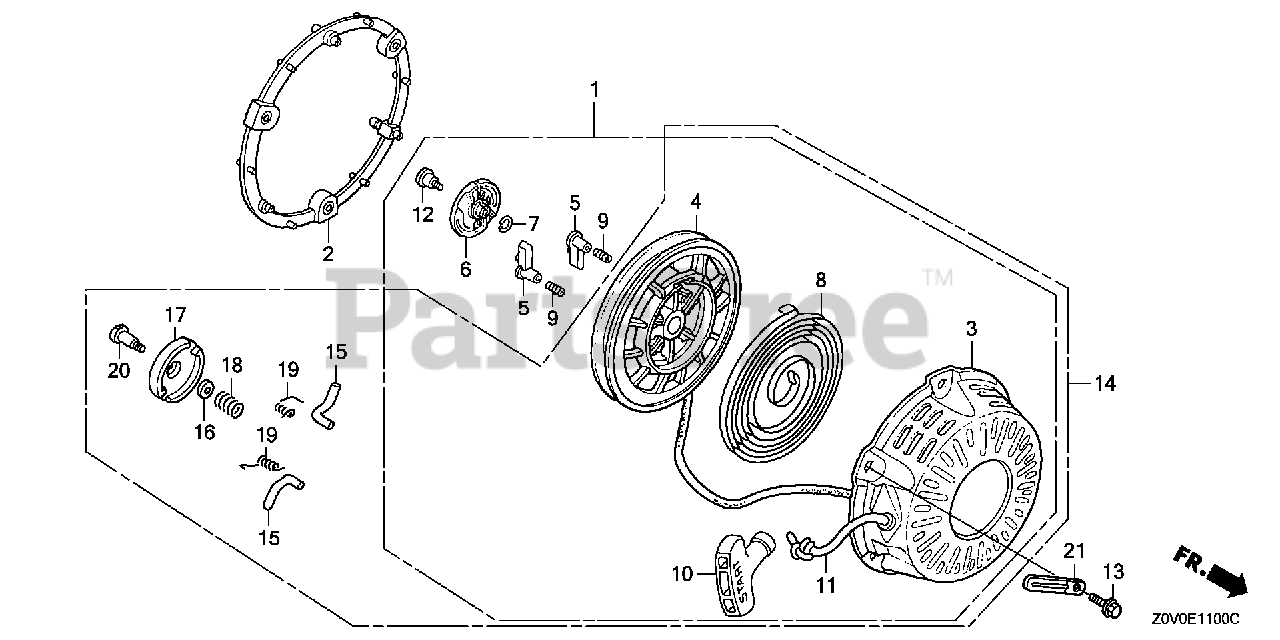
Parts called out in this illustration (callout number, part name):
2	SPACER, RECOIL STARTER MOUNTING *NH1* (BLACK)
2	SPACER, RECOIL STARTER MOUNTING *R280R* (POWER RED)
3	CASE, RECOIL STARTER *R280* (POWER RED)
3	CASE, RECOIL STARTER *NH1* (BLACK)
4	REEL, RECOIL STARTER (BLACK)
8	SPRING, RECOIL STARTER
10	GRIP, STARTER
10	KNOB, RECOIL SRARTER
11	ROPE, RECOIL STARTER
13	BOLT, FLANGE (6X18)
14	STARTER ASSY., RECOIL *NH1* (BLACK)
14	STARTER ASSY., RECOIL *R280* (POWER RED)
15	RATCHET, STARTER
16	PLATE, FRICTION
17	GUIDE, RATCHET
18	SPRING, FRICTION
19	SPRING, RETURN
20	SCREW, SETTING
